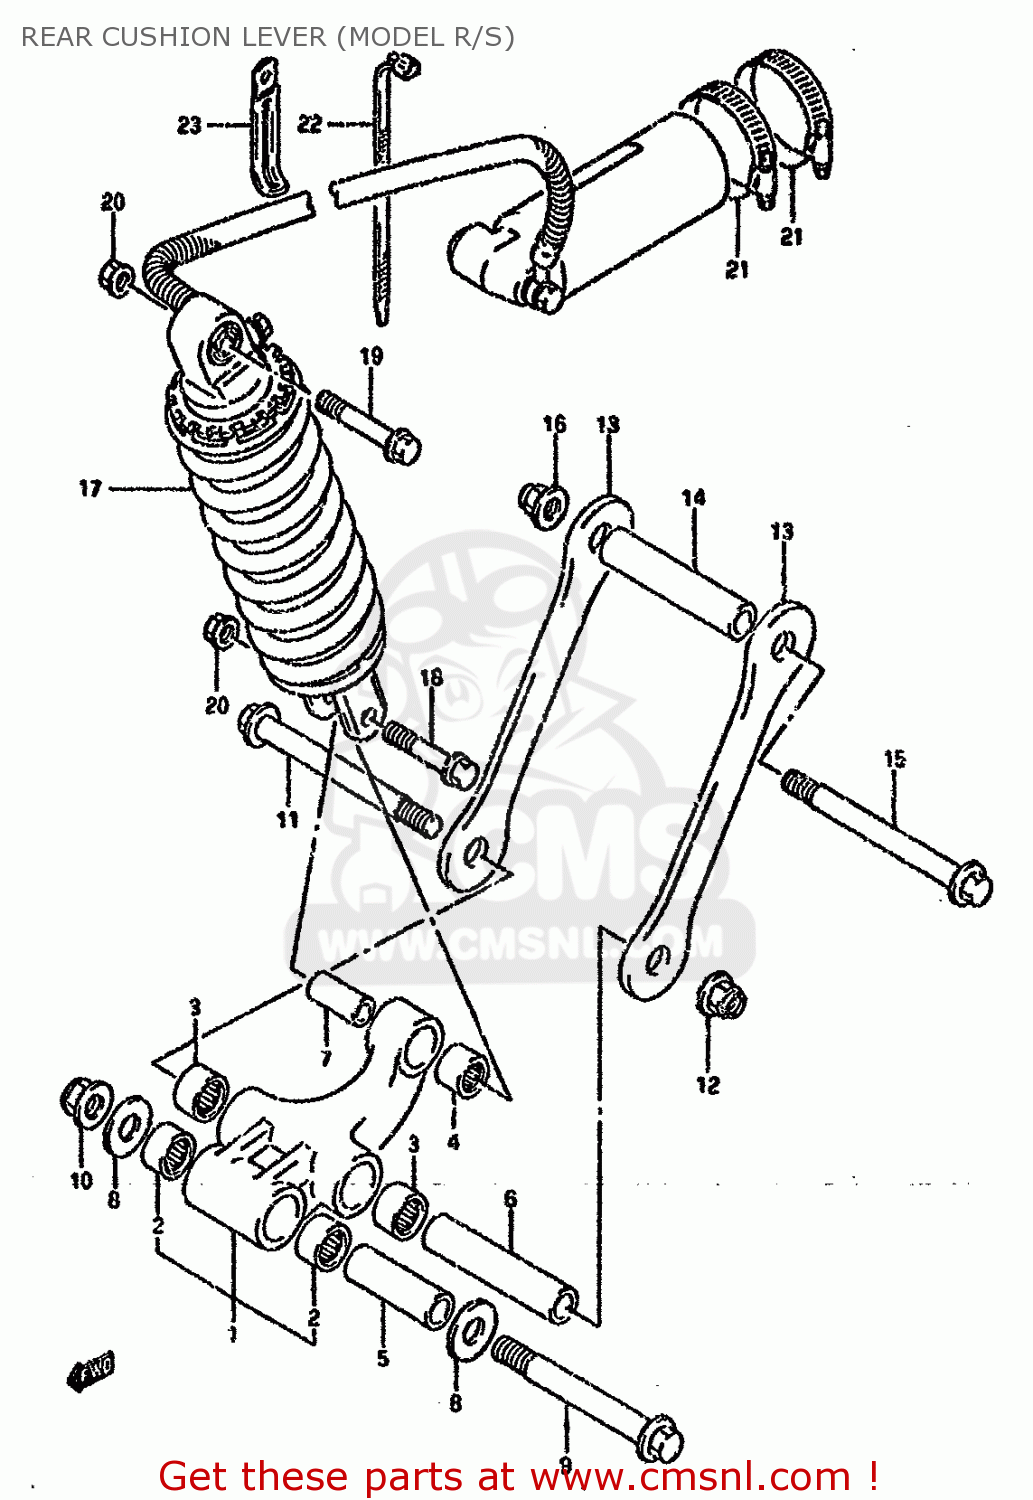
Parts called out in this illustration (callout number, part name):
1	LEVER SET,REAR CUSHION
2	BEARING(20X27X23.5)
3	BEARING(17X24X20)
4	BEARING(17X24X26)
5	SPACER,RR CUSHION LEVER
6	SPACER(12X17X85)
7	SPACER,RR CUSHION LEVER
8	WASHER
9	SHAFT,RR CUSHION LEVER FR
10	NUT
11	BOLT(12X115)
12	NUT 12MM
13	ROD,REAR CUSHION
14	SPACER(12X17X85)
15	BOLT(12X115)
16	NUT 12MM
17	ABSORBER ASSEMBLY,REAR SHOCK
18	BOLT(10X54)
19	BOLT(10X75)
20	NUT
21	CLAMP
22	CLAMP L:165
23	CLAMP(L:80)
